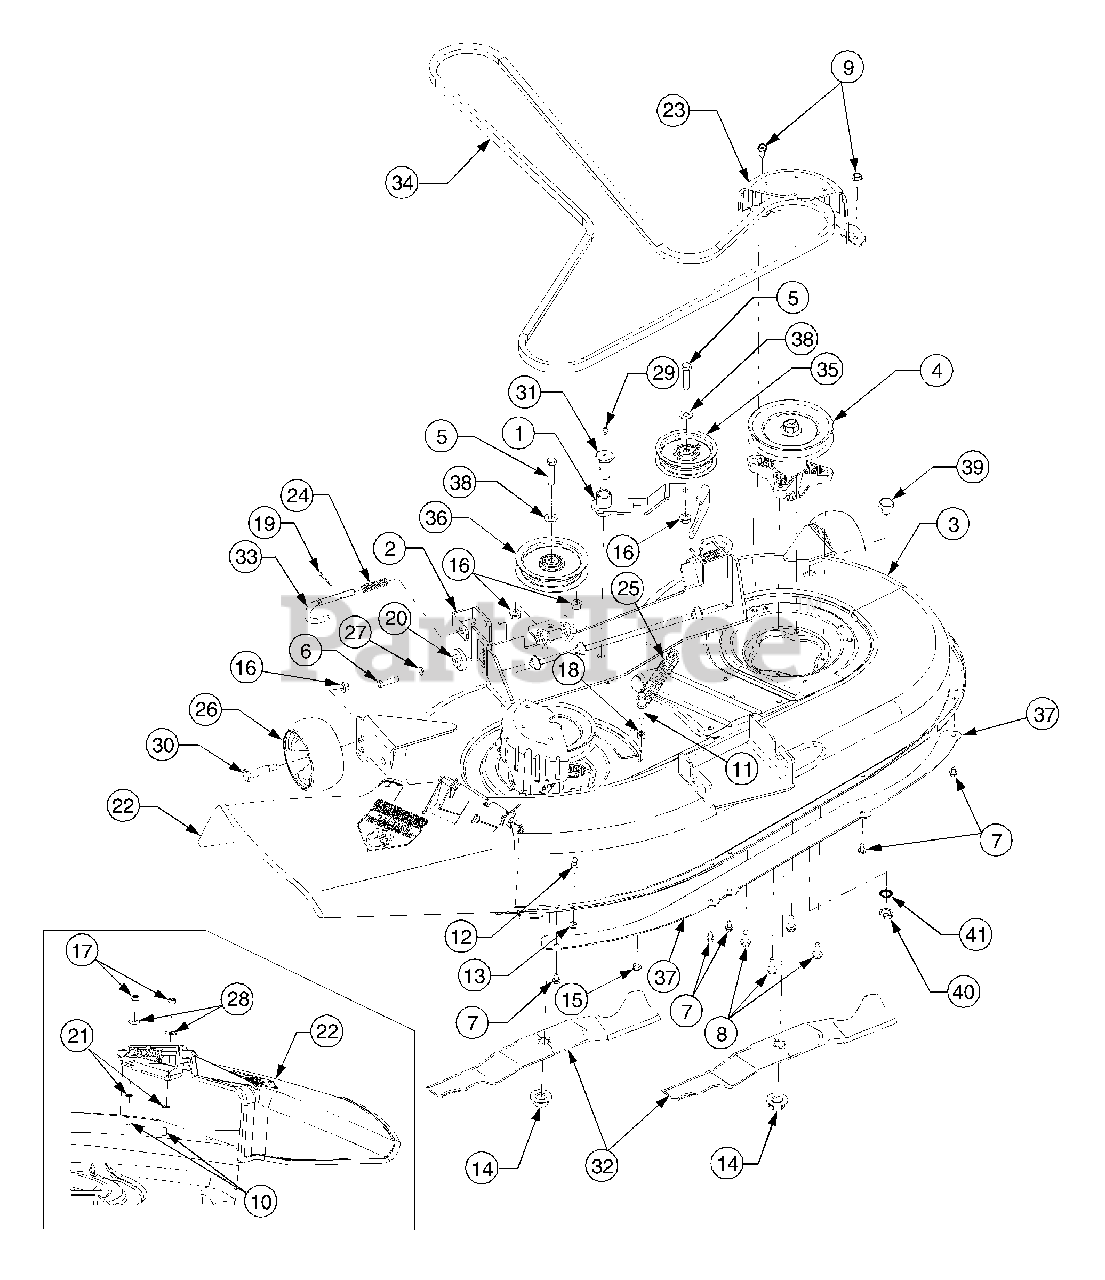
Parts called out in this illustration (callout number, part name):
4	Spindle Assembly
5	Screw, Hex Cap, 3/8-16 x 1.75 GR5
6	Screw, Hex Cap, 5/16-18 x 1.25 GR5
7	Screw, Hex Wash. Hd. Tapp 1/4-20 x .5
8	Screw, Hex Wash. Hd. Tapp 5/16-18 x .875
9	Screw, Hex Wash. Hd. Tapp 5/16-12 x 75
10	Screw, Hex Cap, 1/4-20 x .62 GR5
11	Screw, Hex Cap, 5/16-18 x 1.75 GR5
12	Pin, Grass Catcher, 1/4-20
13	Nut, Hex Insert Lock, 1/4-20 GR8
14	Nut, Hex Flange, 5/8-18
15	Nut, Hex Insert Lock, 5/16-18 GR5
16	Nut, Hex Flange, 3/8-16 GRF
17	Nut, Hex, 1/4-20 GR5
18	Nut, Hex, 5/16-18 GR5
19	Pin, Cotter, 1/8 x 1.25
20	Gear, Deck Adjustment
21	Nut, Push, .25 x .5
22	Chute Assembly, Discharge
24	Spring, Compression
25	Spring, Extension, .94 Dia. x 6.74
26	Wheel, Deck Ball, 5.0
27	Washer, Lock, 5/16
28	Washer, Bell, .265 x .75 x .062
29	Fitting, Lube, 3/16 Drive
30	Screw, Shoulder, .498 x 1.53:3/8-16
31	Screw, Shoulder, .68 x 1.59
32	Blade, Hi-Lift, 21.23
32	Blade, 3 in 1, 21.23
33	Rod, Deck Hanger
34	Belt, V, Type A Sec x 109
35	Pulley, Idler, 3.5 Dia.
36	Pulley, Idler, 4.06 Dia
38	Washer, Flat, .38 x .93 x .11 HT
39	Nozzle, Deck Water
40	Nut, Hex, M16-1.5
41	Washer, Lock,
